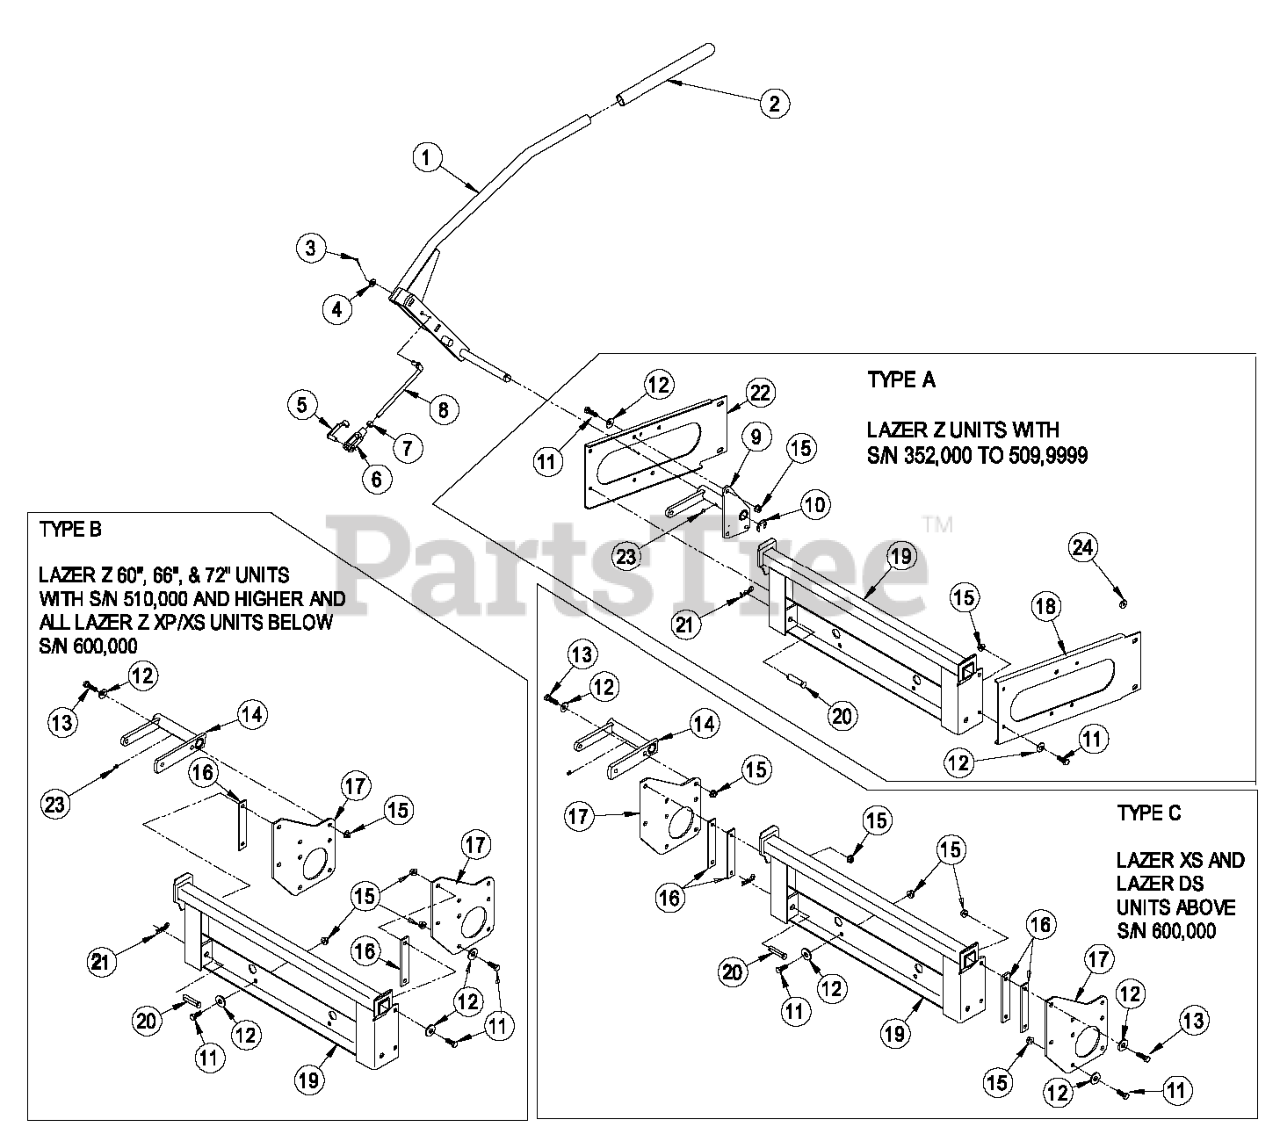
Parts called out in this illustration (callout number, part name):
1	HANDLE AND GRIP ASM
2	GRIP-HANDLE
3	PIN-COTTER
4	WASHER-FLAT
5	PIN-SPRING, CLEVIS
6	YOKE-LINKAGE, BRAKE
7	NUT-HEX
8	LINK-HANDLE
9	WLD, HANDLE MOUNT
11	SCREW-HH
12	WASHER-BELLEVILLE
13	SCREW-HH
14	WLD, HANDLE MOUNT - XP
15	NUT-HHF, WHIZ
17	PLATE-MOUNT, BAGGER
18	BRACKET-FRAME, RH
19	MOUNT-BAGGER
20	PIN-CLEVIS
21	PIN-COTTER
22	BRACKET-FRAME, LH
23	FITTING-GREASE
